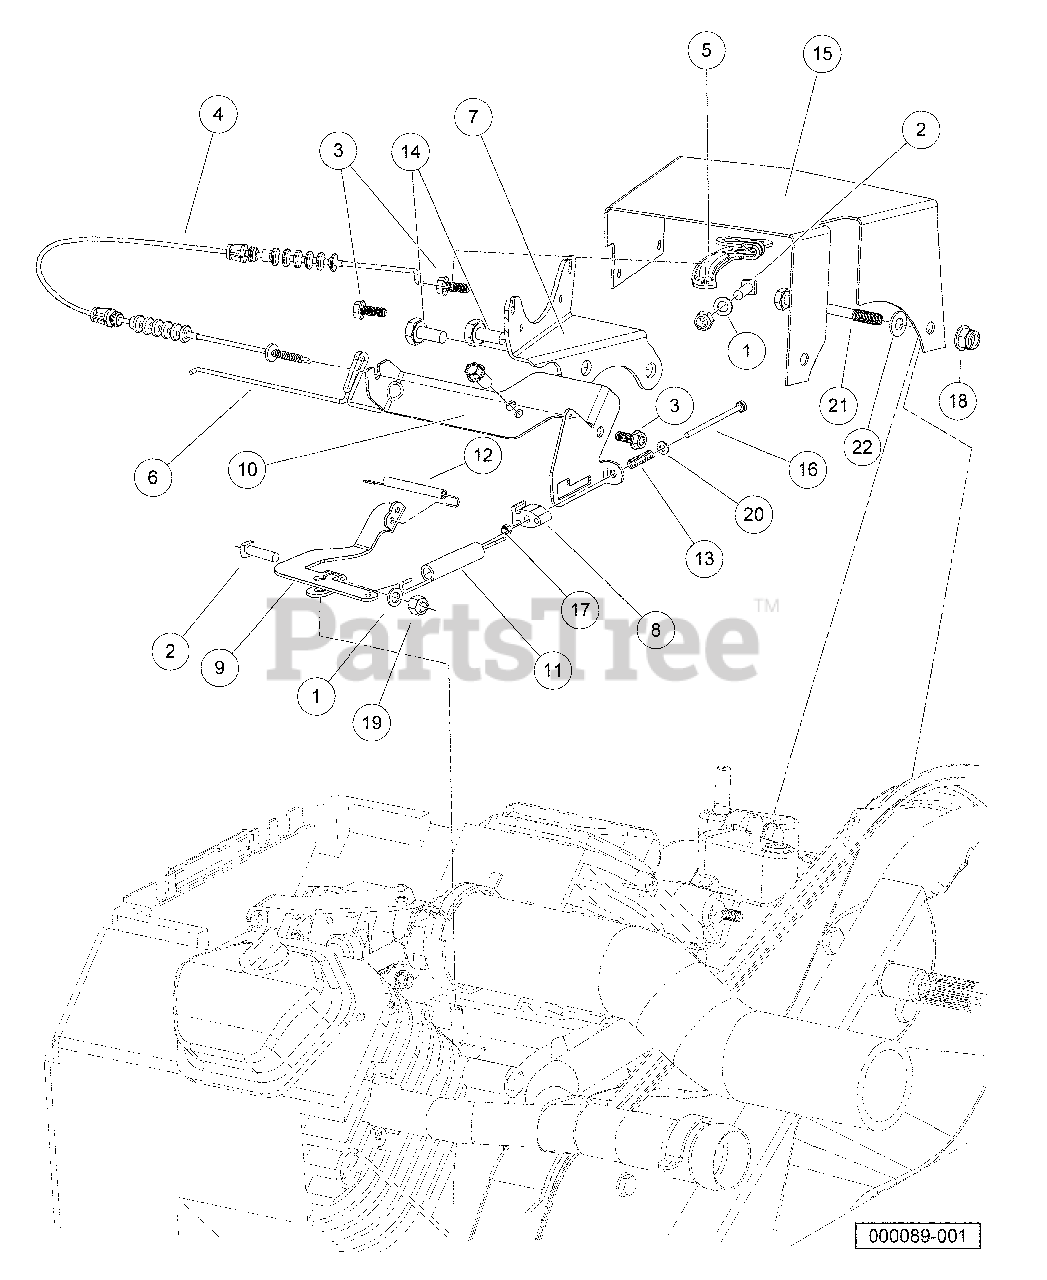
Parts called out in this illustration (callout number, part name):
1	Washer, 1/4 Flat
2	Screw, 1/4-20 X 1.00 Square-Head
3	Screw, M6 X 16 Tt Hx Fl Hd
4	Cable, Engine Governor
5	Bracket, Governor, Arm, Trans
6	Wire, Governor
7	Bracket, Governor, Trans Cable
8	Adjuster, Spring, Idle
9	Bracket, Arm, Gov, Engine
10	Bracket, Cable, Gov, Engine
12	Spring, Carb
13	Spring, Compression, Adj, Idle
14	Bolt, M10 X 1.5 X 20 Loctite
15	Guard, Governor, Ground Speed
16	Bolt, M4 X .7 X 60
17	Nut Flg, M4 X 0.7 Mech Def
18	Lock Nut, Flg M8 X 1.25 Nylon
19	Locknut, 1/4-20 Nylon Insert
20	Washer, M4
21	Bolt, M8 X 1.25 X 80
22	Washer, M8 Hard
